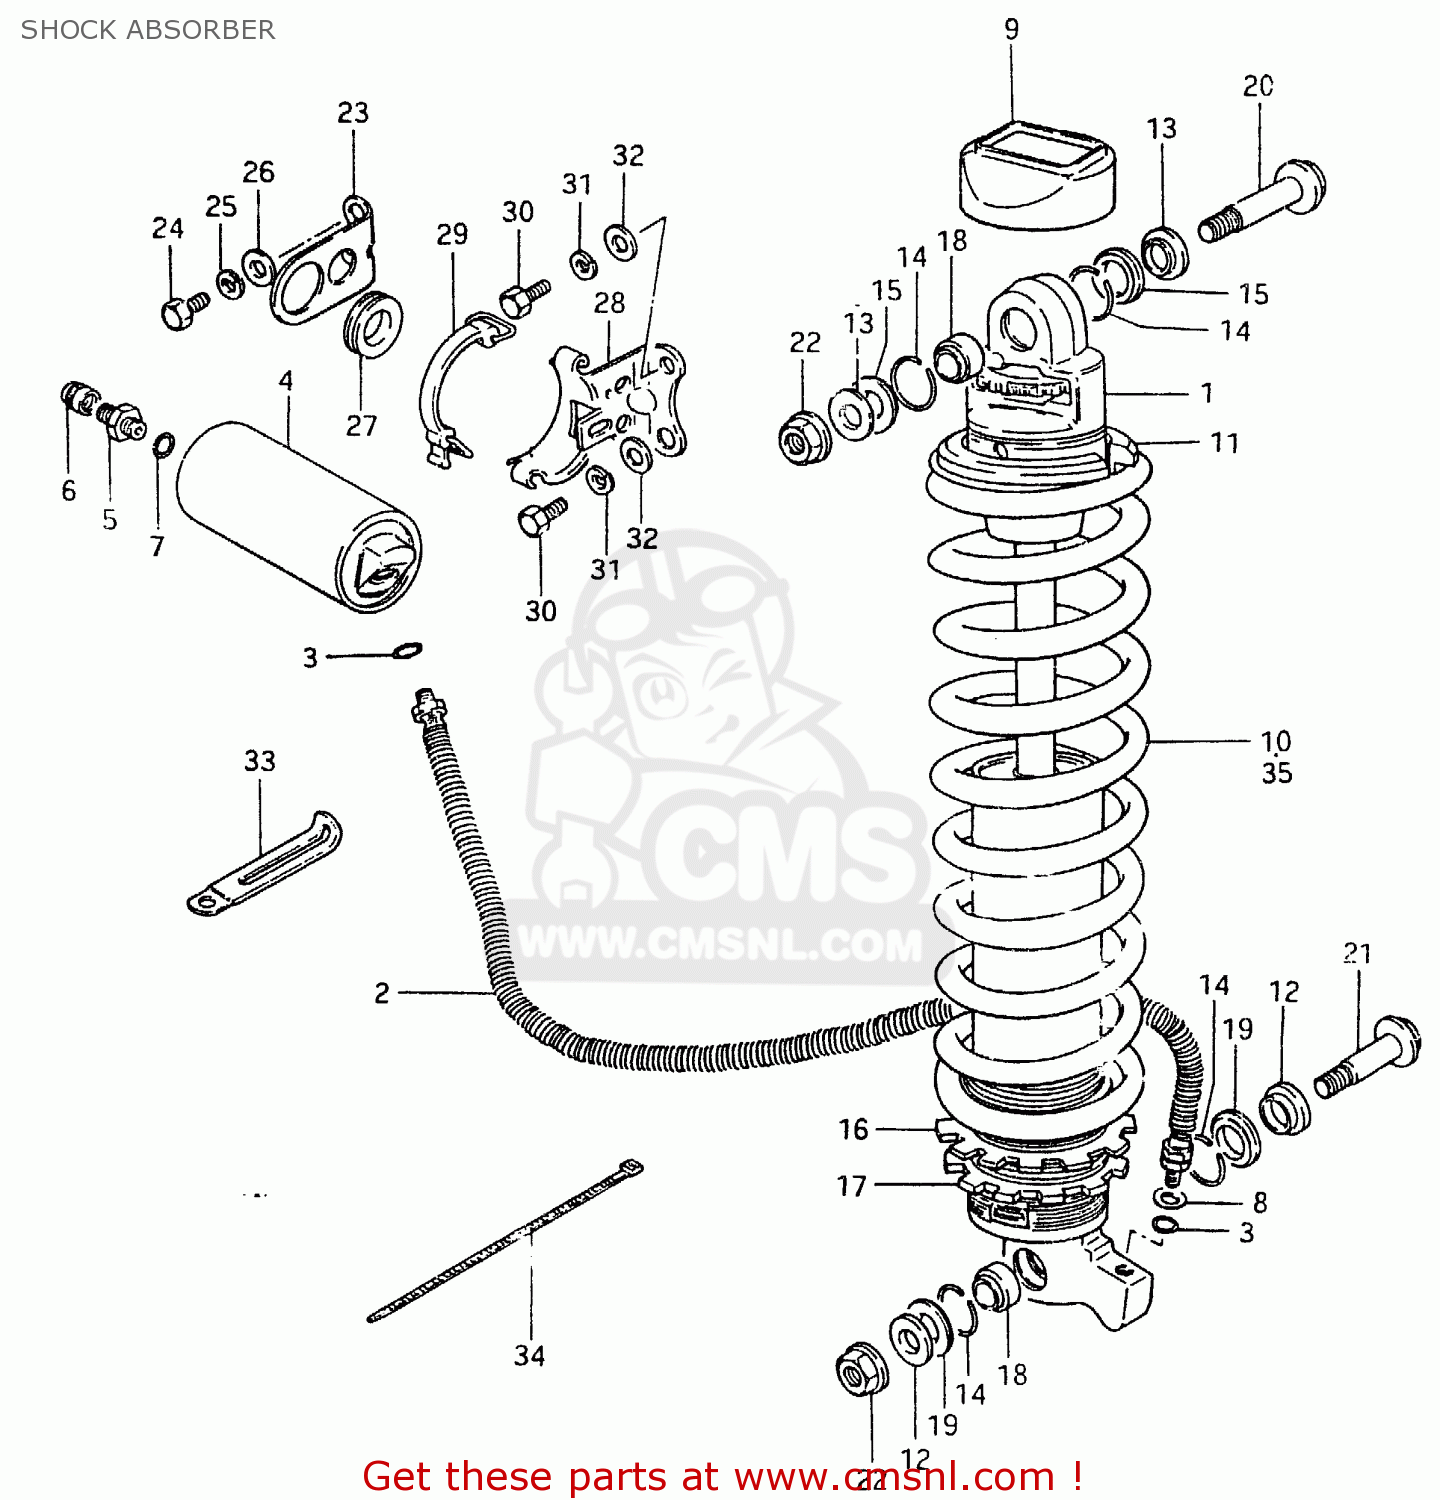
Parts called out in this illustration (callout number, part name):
1	ABSORBER ASSEMBLY,REAR SHOCK
2	HOSE,REAR SHOCK ABSORBER
3	O-RING,RESERVE TANK
4	RESERVE TANK,REAR SHOCK
5	VALVE ASSEMBLY,REAR CUSHION
6	CAP,VALVE AIR
7	O RING
8	WASHER,REAR SHOCK HOSE
9	CAP REAR SHOCK
10	SPRING
11	SPRING, GUIDE
12	COLLAR
13	SPACER,REAR SHOCK,UPPER
14	RING
15	DUST SEAL,UPR
16	GUIDE,SPRING
17	GUIDE,REAR SHOCK ABSORBER SPRING
18	BEARING
19	DUST SEAL,LWR
20	BOLT
21	BOLT(10X54)
22	NUT
23	BRACKET,RESERVOIR TANK
24	BOLT
25	LOCK WASHER
26	WASHER
27	CUSHION,RESERVOIR TANK
28	BRACKET,RESERVOIR TANK
29	BAND
30	BOLT
31	LOCK WASHER
32	WASHER
33	CLAMP
34	CLAMP
35	SPRING
